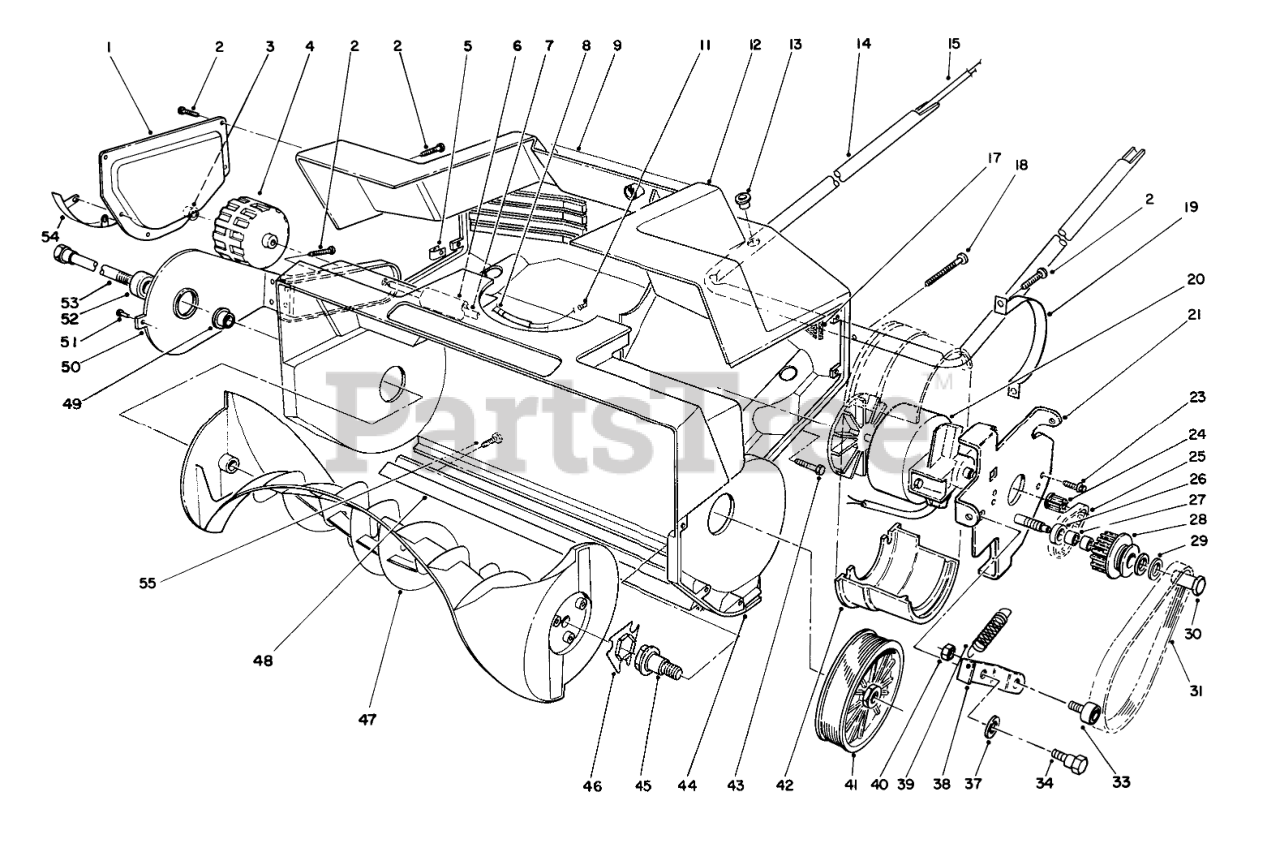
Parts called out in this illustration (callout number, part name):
1	PLATE - SIDE, PAINTED
2	Screw
3	PUSHNUT-CAP, WASHER
4	Wheel
5	U-CLIP
6	SLEEVE, AXLE
7	Shaft-Axle
8	Relief-Strain
9	Decal-Danger
11	Connector
12	SHROUD W/O AMP LABEL
13	BUSHING
14	Tube-Lower Handle
15	Wire Harness
17	Filter-Foam
18	Screw-Pan Head
19	Strap-Motor
20	Motor
21	Motor Plate ASM
23	Screw-Hex Washer Hd.
24	Pulley-Driver
25	BELT-PULLEY, IDLER/DRIVER
26	WASHER
27	Bearing
28	PulleyAssembly-Idler (Incl. Ref. #27)
29	WASHER-THRUST
30	Bolt-Idler
31	Belt-Drive
33	Bearing Assembly (Incl. Ref. #40)
34	SCREW-SHOULDER
37	WASHER
38	Bracket-Idler
39	Spring
40	NUT-LOCK, NI
41	Pulley-Driven
42	Clamp-Motor Bracket
43	SCREW-HH
44	Housing-Rotor
45	Shaft-Driver, Rotor
46	Coupler-Rotor
47	Rotor
48	Scraper
49	BUSHING
50	Bracket-Wheel (Incl. Ref. #52)
51	RIVET-POP
52	Bearing-Ball
53	Shaft-Rotor
54	Skid-Housing
55	Screw-Pan Head
